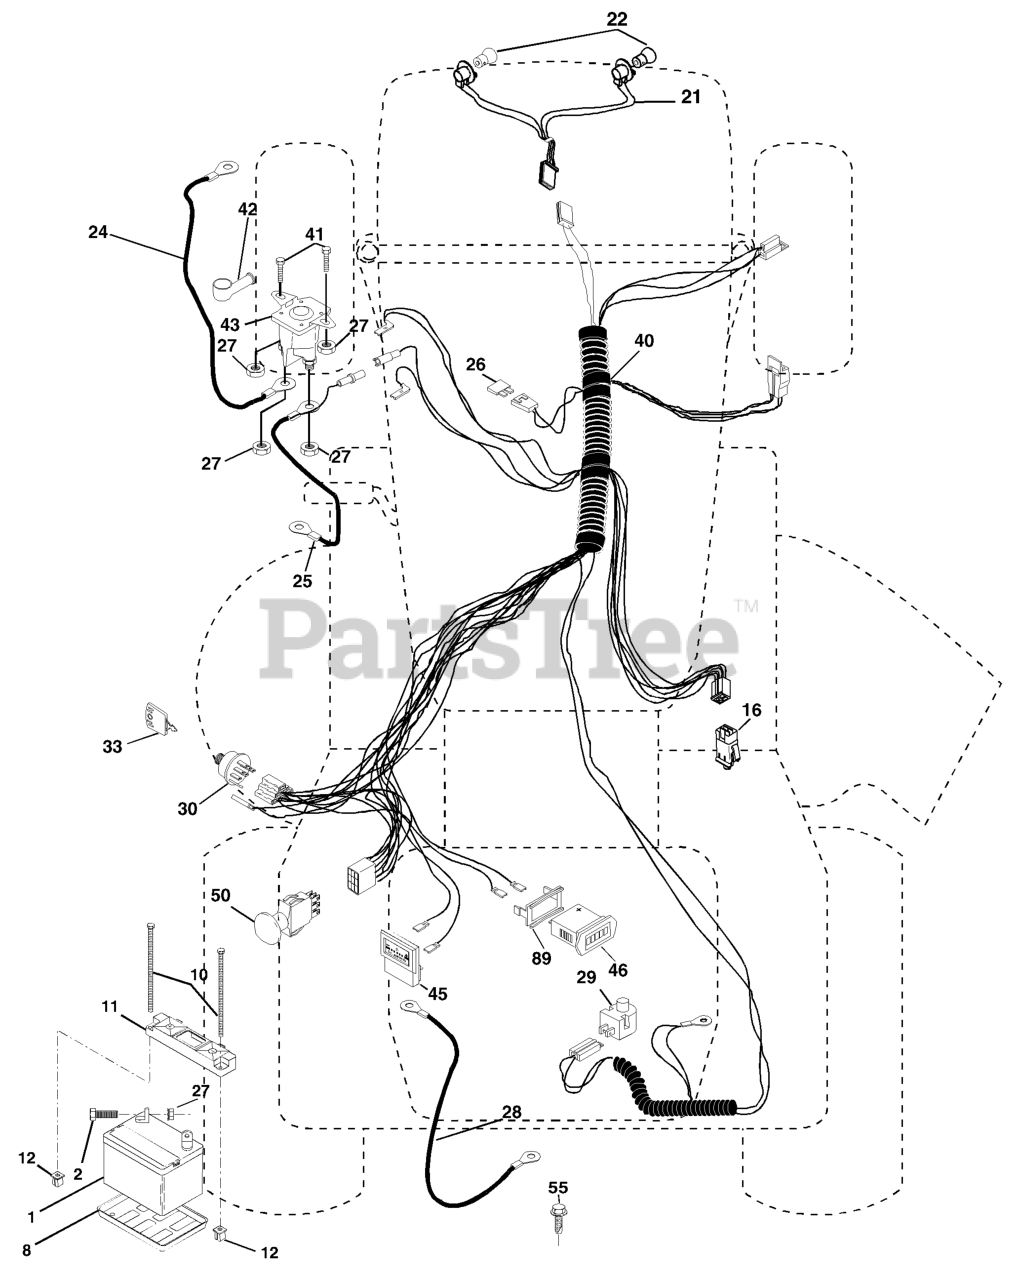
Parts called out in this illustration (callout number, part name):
1	BATTERY 12V .35 AMP
2	BOLT.HEX.1/4.X.3/4.DICHROMATE
8	BATTERY TRAY T
10	BOLT 1/4-20 X 7.5
11	BATTERY HOLDDOWN FRONT MOUNT
12	NUT, PUSH NYLON 1/4" BATTERY
16	SWITCH INTERLOOK PUSH-IN
21	HARNESS ASSY LIGHT
24	BATTERY CABLE GT
25	CABLE BATTERY 6 GA 22" W/16W
26	FUSE 20AMP
27	NUT
28	CABLE GROUND 6 GA 21" 90T BLK
29	RP.SWITCH.PLUNGER.NC.GRAY
30	IGNITION SWITCH
33	KEY MLD GEN DELTA
40	HARNESS.IGNITION
41	BOLT
42	TERMINAL COVER
43	SOLENOID
46	HOUR METER
50	RP.PTO.SWITCH.8 TERMINAL.BLACK
55	Screw 5/16-18 x 1/2
89	BRACKET SNAP-IN HOURMETER
